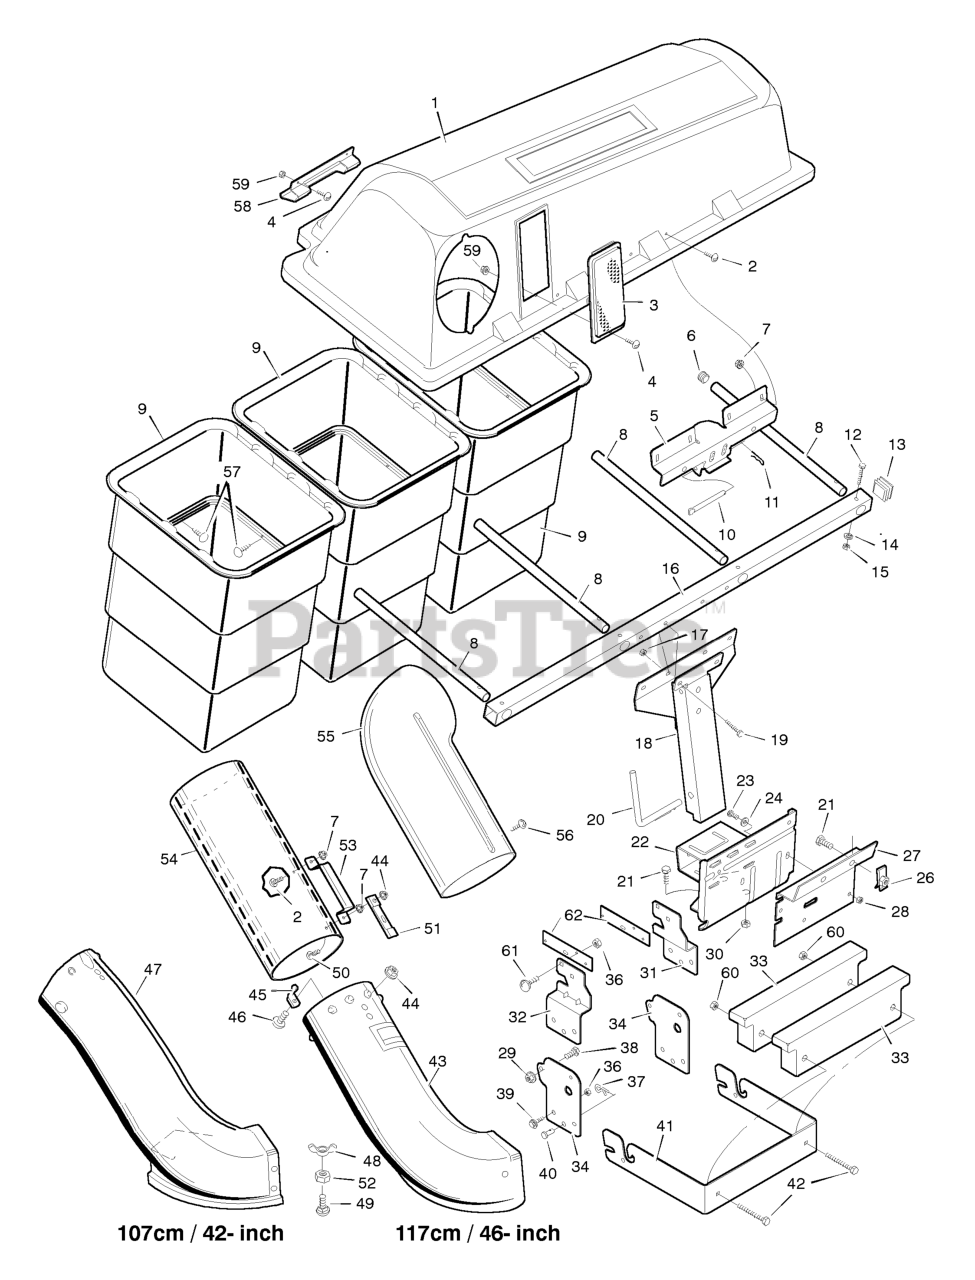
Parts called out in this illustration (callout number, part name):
1	Cover, Bagger
5	Hinge, Bracket
7	Nut, Hex
8	Tube, Container
9	Container
10	Pin, Hinge
11	Pin, Hair
13	Plug
14	Lockwasher
16	Tube, Support
17	Nut
18	Channel Assembly
20	Pin, Channel Mount
21	Bolt, Hex
22	Plate, Mounting
23	CAPSCREW, Hex Head, 5/16-18 x 1
24	Washer
27	Adapter, Mounting Plate
28	Nut, Flange
29	Nut, Flange
30	Nut, Hex
31	Bracket, Left Hanger
32	Bracket, Right Hanger
33	Weight, Front
34	Bracket, Hanger
36	Nut
37	Pin, Hair
38	Bolt
40	Pin, Clevis
41	Bracket, Front Weight
43	Extension, Chute
44	Locknut, Flange
45	Pin, Latch
46	Bolt, Carriage
47	Extension, Chute
48	Wingnut
49	Bolt, Carriage
51	Latch, Rubber
53	HANDLE, Connect Tube
54	Tube, Connecting
57	Fastener, Panel
58	Handle, Plastic
59	Nut, Hex
60	Nut
62	Plate, Support
63	Blade, (117cm / 46-inch)
